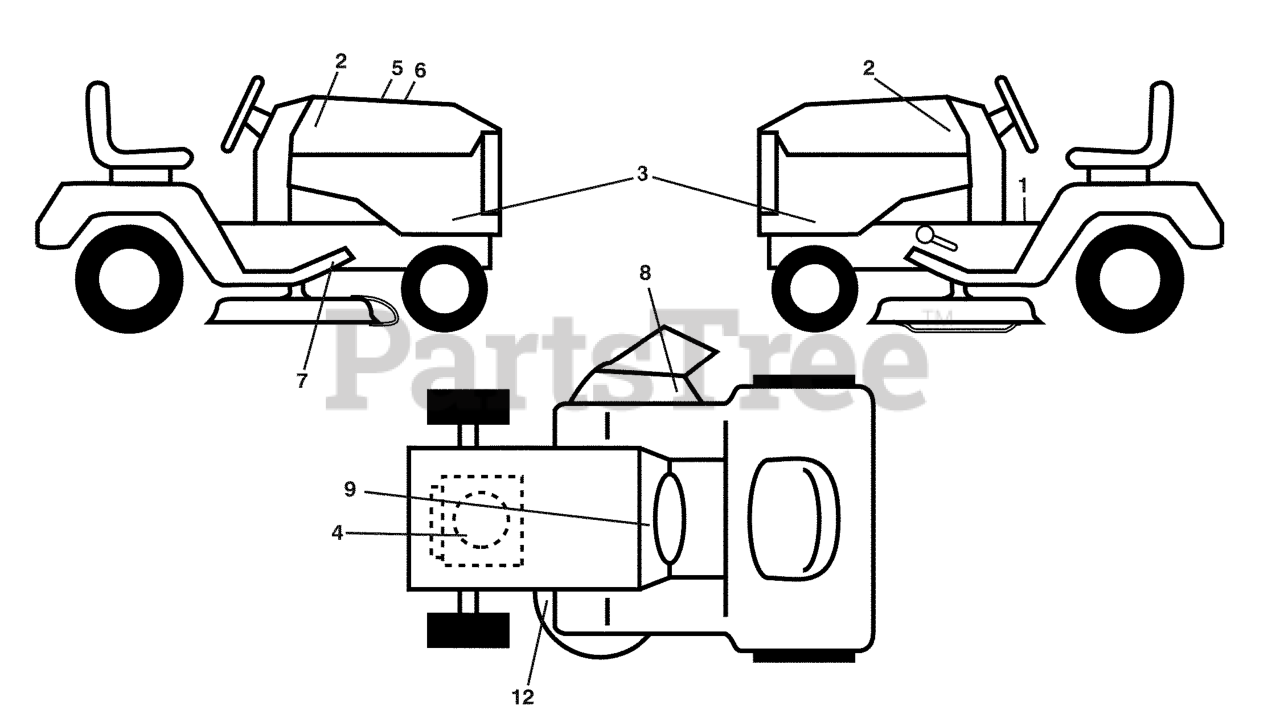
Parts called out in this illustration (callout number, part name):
1	DECAL.FENDER.WARNING.ENG
2	RP EMBLEM, HOOD
3	DECAL.SDPNL.2246LS.ENDUR.HUSQV
4	DECAL.ENG.BSM40.ENDUR.278169
5	DECAL.WARNING.CUST.RESP.E85.
6	DECAL.RPL.
7	DECAL.PEDAL.HUSQ.CROWN
8	DECAL.WARN.KEEP.HAND.AWAY
9	DECAL BTRY SYMBOLS
12	DECAL V BELT SCHEMATIC
